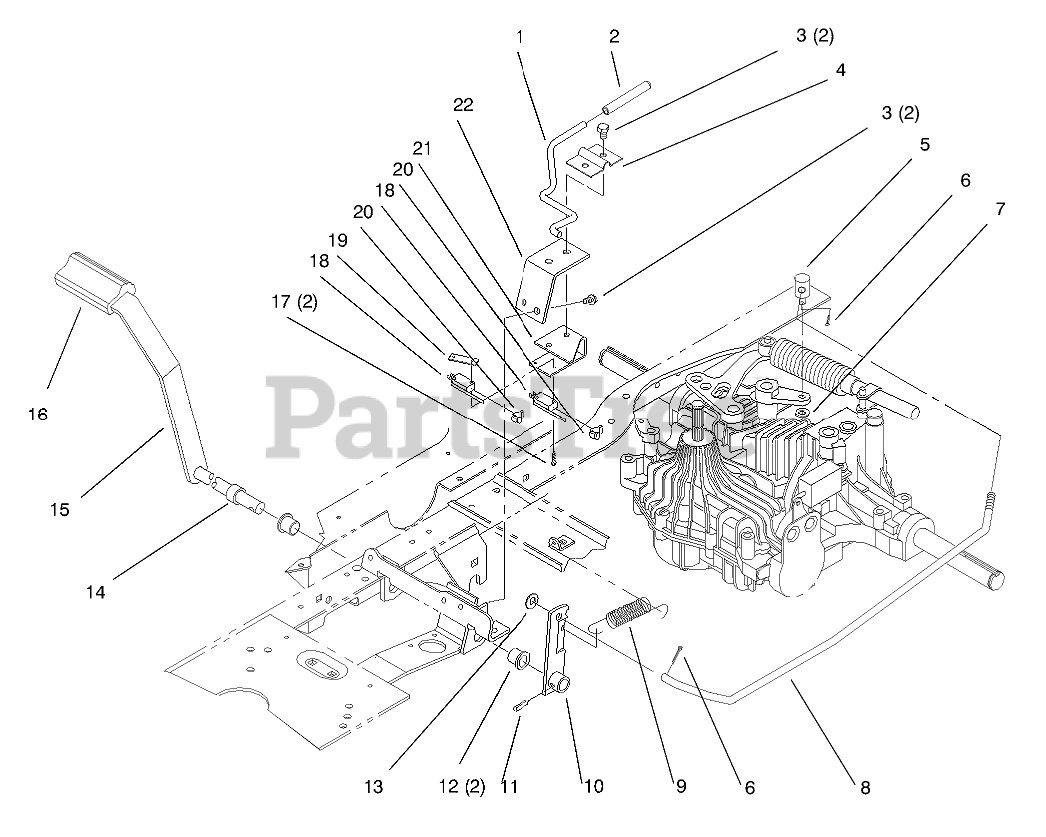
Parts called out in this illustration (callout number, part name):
1	ROD - PARKING BRAKE
2	GRIP - PARKING BRAKE
3	SCREW-HWHTF
4	BRKT-PARKING BRAKE
5	TRUNNION - BRAKE
6	PIN-COTTER
7	WASHER-PLAIN
8	ROD - BRAKE
9	SPRING-EXTENSION
10	WA - BRAKE LEVER
11	PIN-SPRING
12	BUSHING-FLANGE
13	WASHER-FLAT
14	SPACER-BRAKE
15	LEVER - BRAKE WA
16	PAD-PEDAL
17	SCREW-HH
18	SWITCH-MICRO
19	NUT-SPEED
20	PLUNGER-SEAL
21	BRKT - BRAKE SWITCH
22	SUPPORT - P. BRAKE
